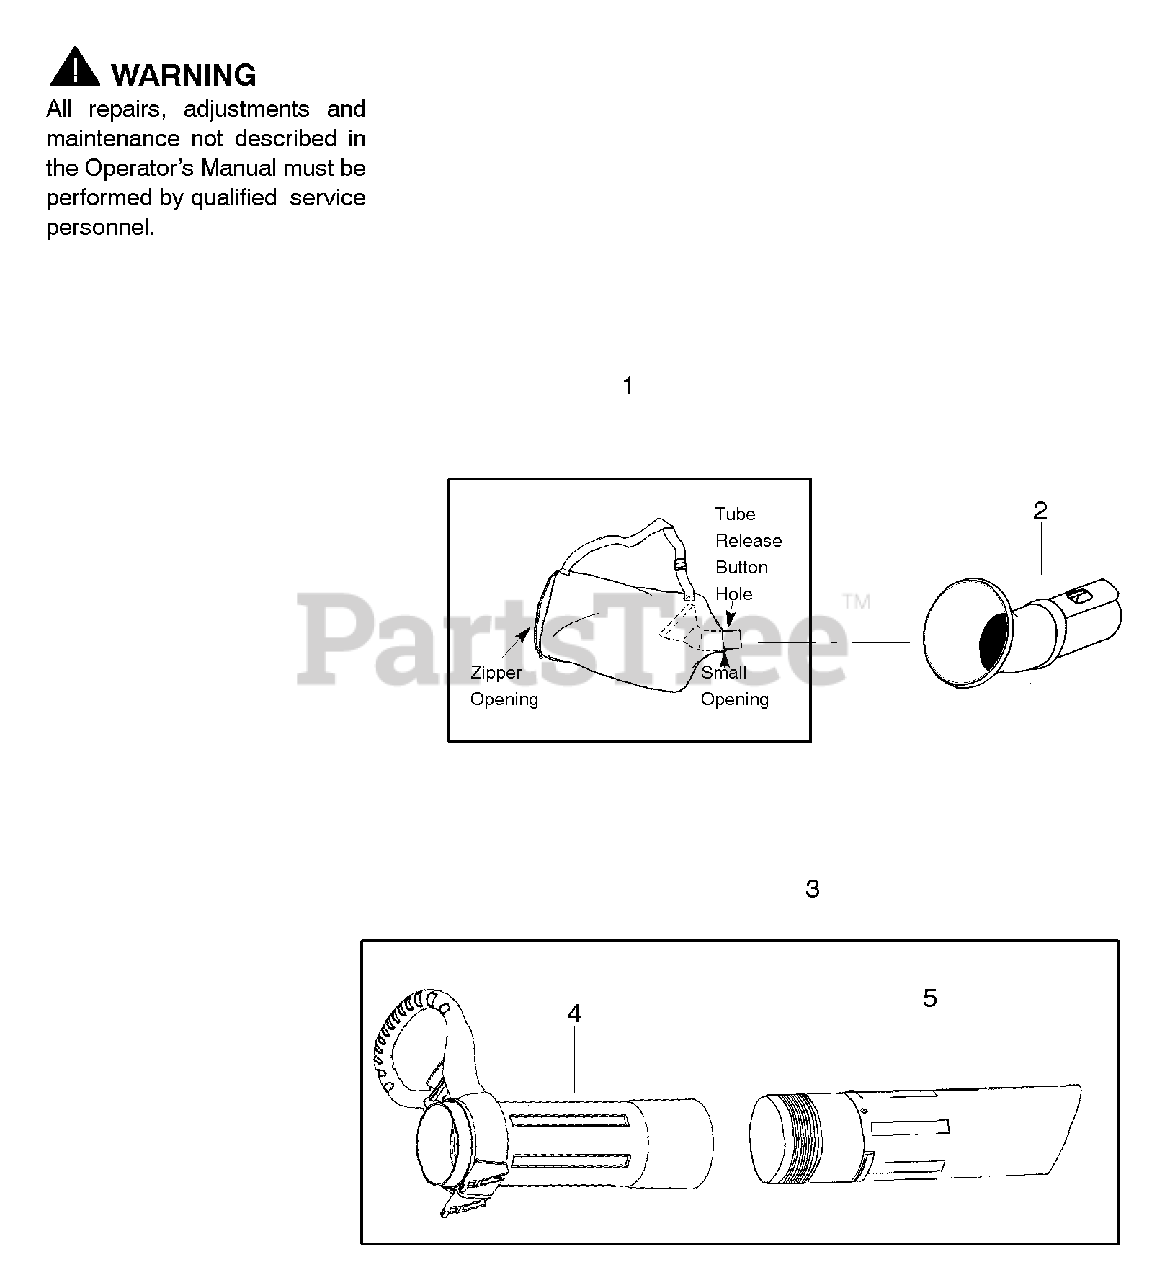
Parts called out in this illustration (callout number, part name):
1	Assy. - Vac Bag
2	Attachment - Vac Bag
3	Kit-Upper/Lower Tube w/handle
4	Tube - Upper Vac w/handle
5	Tube - Lower Vac
